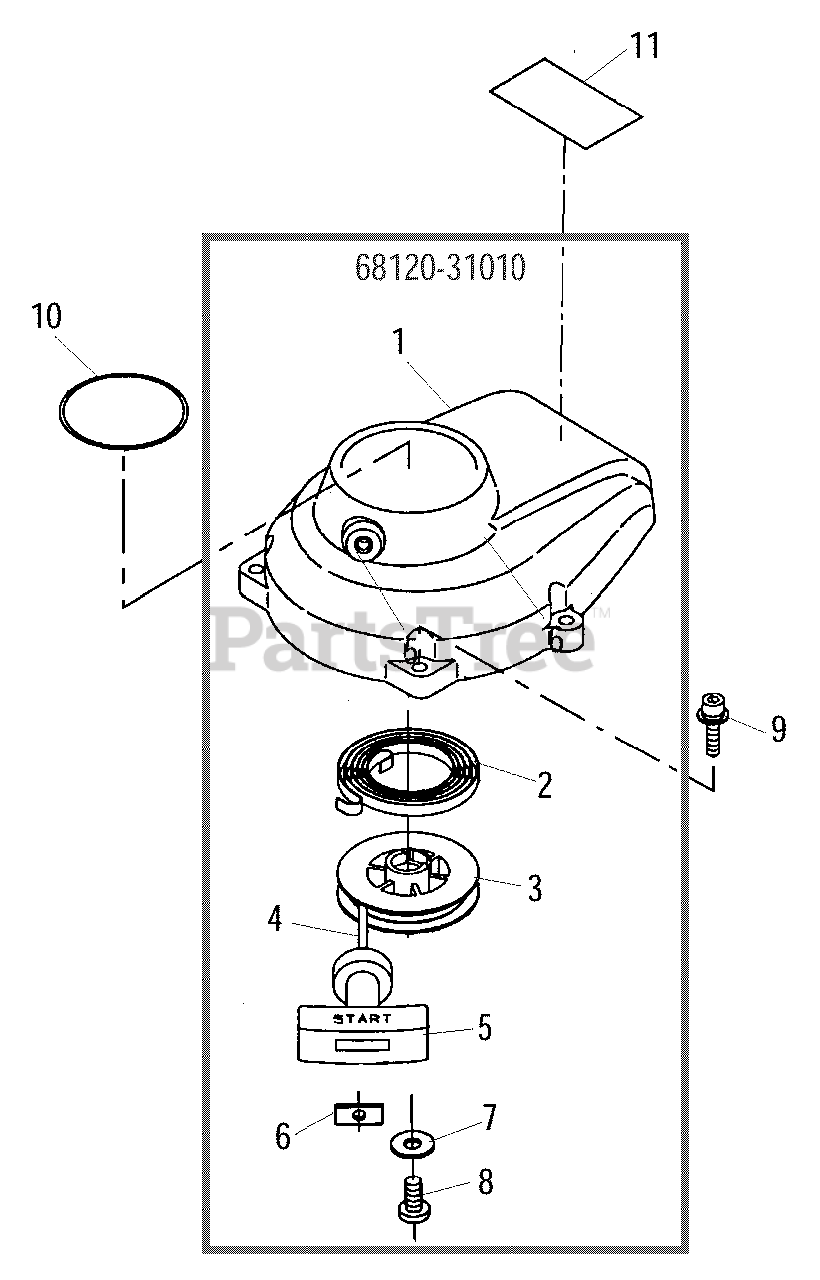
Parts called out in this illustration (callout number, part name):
1	CASE, STARTER
2	SPRING, RECOIL
3	REEL, ROPE
4	ROPE, STARTER
5	GRIP, STARTER
6	RETAINER, ROPE
7	WASHER 5
8	SCREW 5
9	BOLT, ADHESIVE M5×20
10	LABEL - MODEL
11	LABEL - NAME
68120-31010	STARTER ASSY
